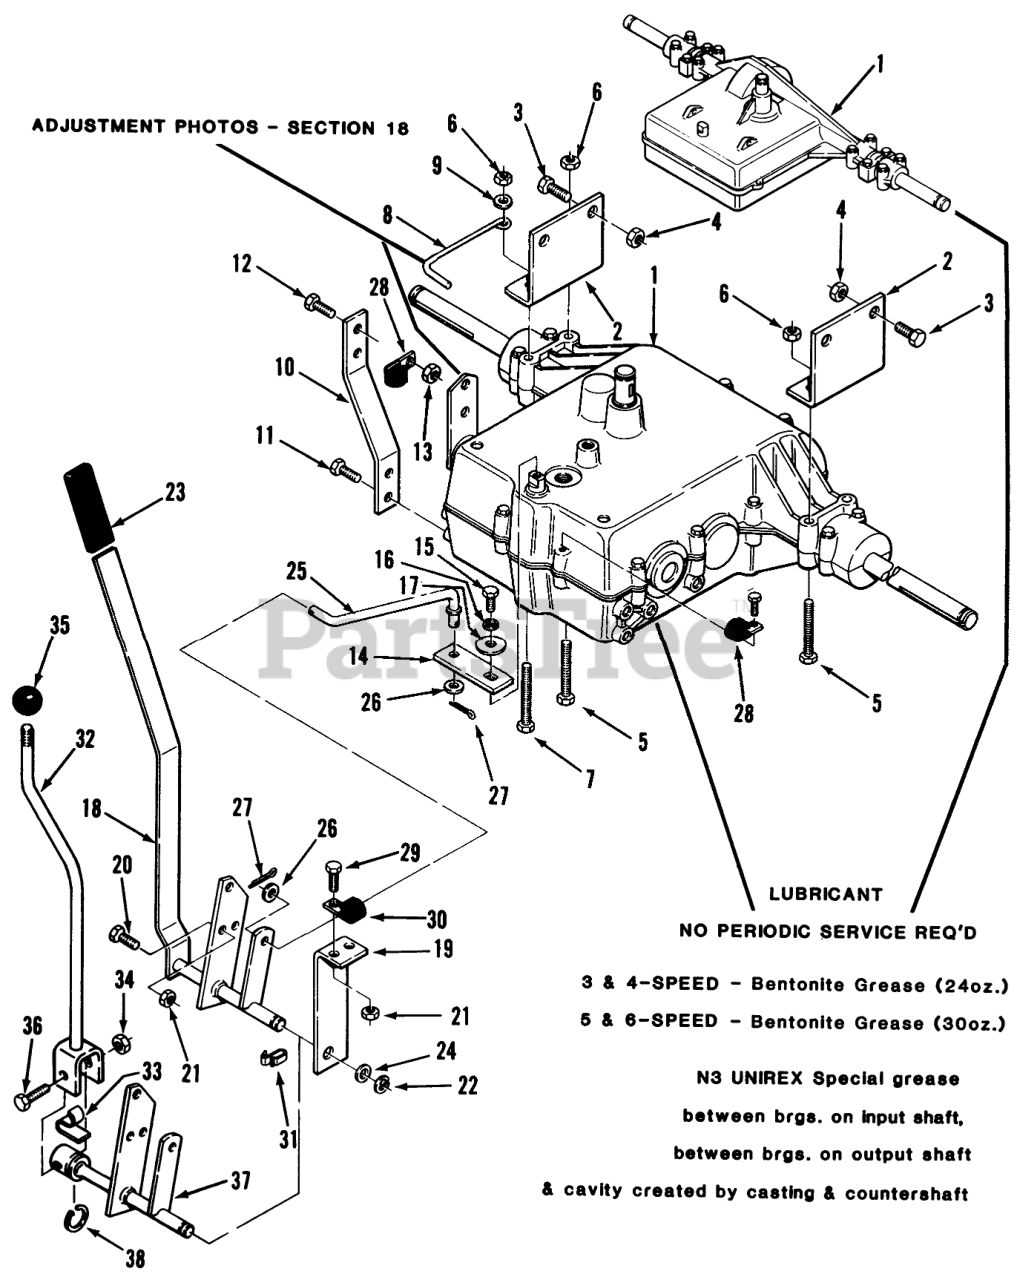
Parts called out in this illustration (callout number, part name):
1	Peerless Transmission (900-012A) 108-3 Only
2	Bracket-Rear Axle
3	BOLR HWH 3/8-16X7/8
4	NUT
5	HHCS
6	Nut
7	Pin-Cotter
8	STOP BRAKE
9	WASHER 5/16 SAE
10	STRAP TORQUE
11	STRAP TORQUE
12	Bolt
13	Nut
14	LEVER LOWER SHIFT
15	Bolt 1/4-28 X 7/8
16	Washer
17	WASHER
18	ASSY LEVER SHIFT R
19	SUPPORT SHIFT
20	Bolt
21	Nut
22	E Ring
24	Washer
25	ROD SHIFT LOWER
26	WASHER 5/16 SAE
27	Cotter Pin
28	J-CLIP
29	BOLT 5/16-18 X 3/4
30	J-CLIP
31	CLIP-CABLE
32	Handle 112-C Only
33	CLIP-SPRING
34	LOCKNUT 5/16-18GR.B
35	KNOB
36	HHCS
37	Shift Lever 112-C Only
38	Snap Ring
